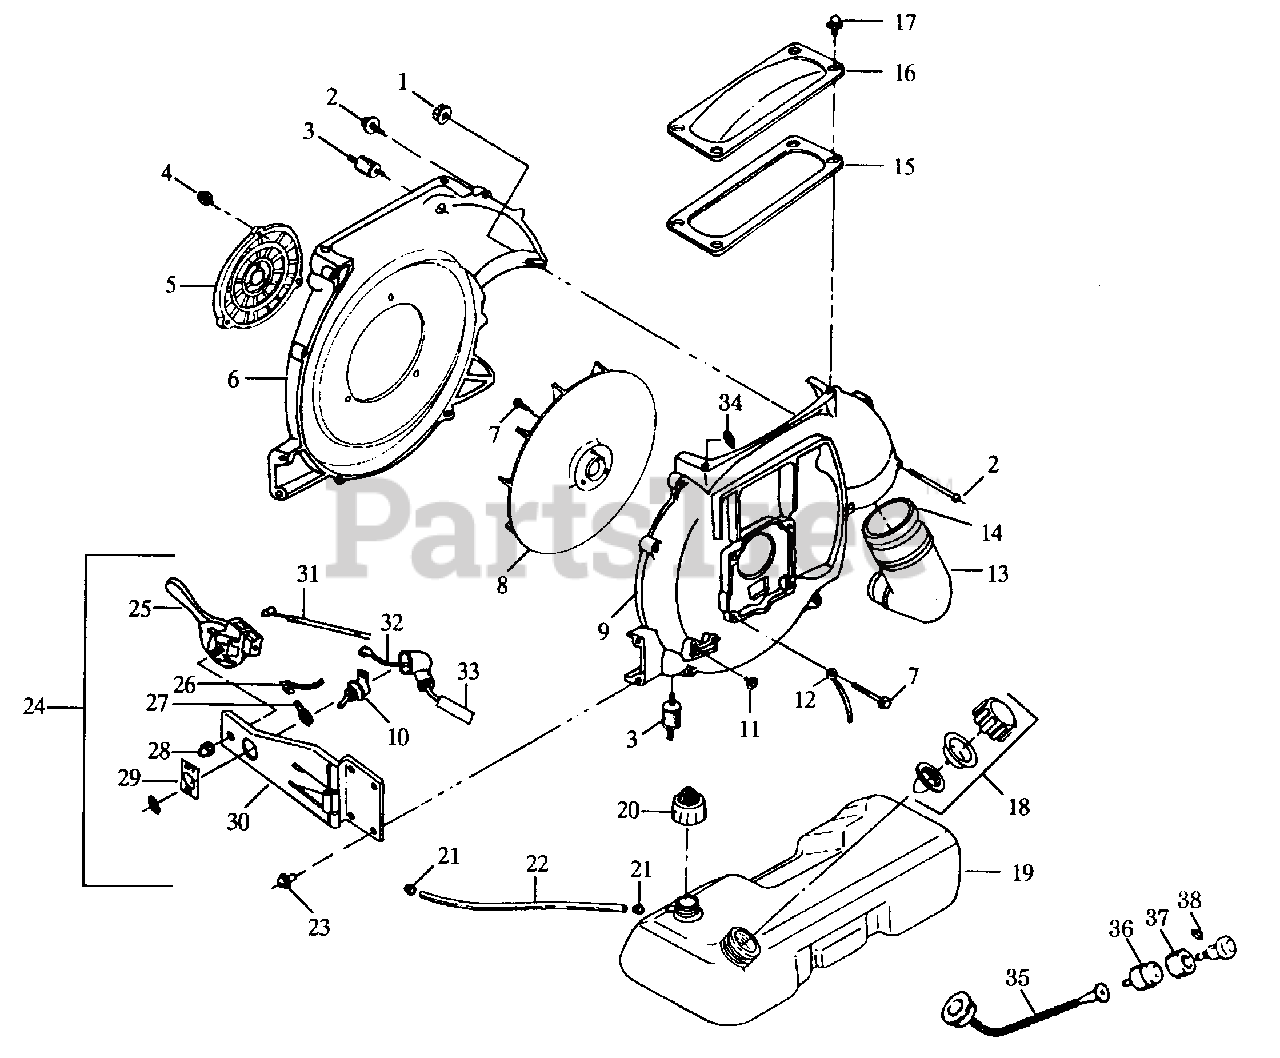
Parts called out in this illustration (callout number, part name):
3	Isolating Rubber
5	Fan Cover
6	Fan Case (R)
9	Fan Case (F)
10	Stop Switch
12	Wire Band
13	Elbow Pipe
14	O Ring
18	Tank Cap Ass'y.
19	Fuel Systems
20	Priming Pump
22	Fuel Tube
24	Lever Holding Ass'y.
25	Throttle Lever
26	Earth Wire
27	Earth Plate
30	Lever Compliance
31	Throttle Wire
32	Lead Wire
35	Suction Hose
36	Fuel Filter
